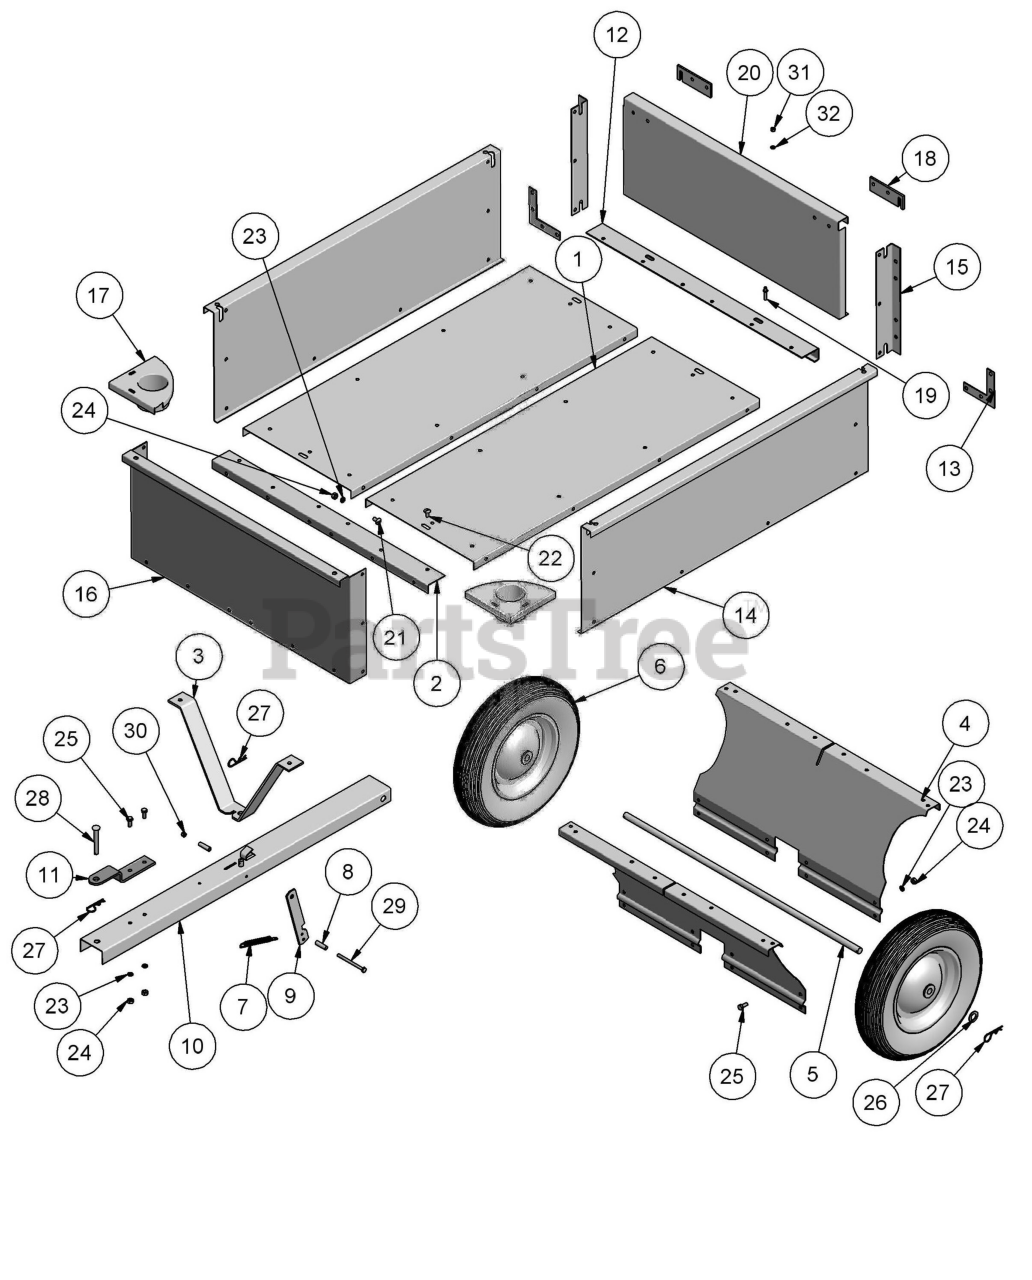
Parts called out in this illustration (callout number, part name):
1	BOTTOM PANEL
2	FRONT CROSS BRACE
3	TONGUE SUPPORT
4	WHEEL AXLE SUPPORT
5	WHEEL AXLE
6	WHEEL/TIRE ASSEMBLY
7	LATCH SPRING
8	LATCH SPACER
9	TONGUE LATCH
10	HITCH TONGUE
11	HITCH PIN BRACKET
12	REAR CROSS BRACE
13	REAR CORNER BRACKET
14	SIDE PANEL
15	REAR CORNER BRACE
16	FRONT PANEL
17	FRONT CORNER BRACE
18	TAILGATE LATCH
19	TAILGATE PIN
20	TAILGATE
21	M8 X 16 TRUSS HEAD BOLT
22	M8 X 20 TRUSS HEAD BOLT
23	8MM LOCK WASHER
24	8MM HEX NUT
25	M8 X 20 HEX BOLT
26	20MM FLAT WASHER
27	3MM HAIRPIN
28	HITCH PIN
29	M6 X 90 HEX BOLT
30	6MM NYLON NUT
31	6MM HEX NUT
32	6-8MM FLAT WASHER
